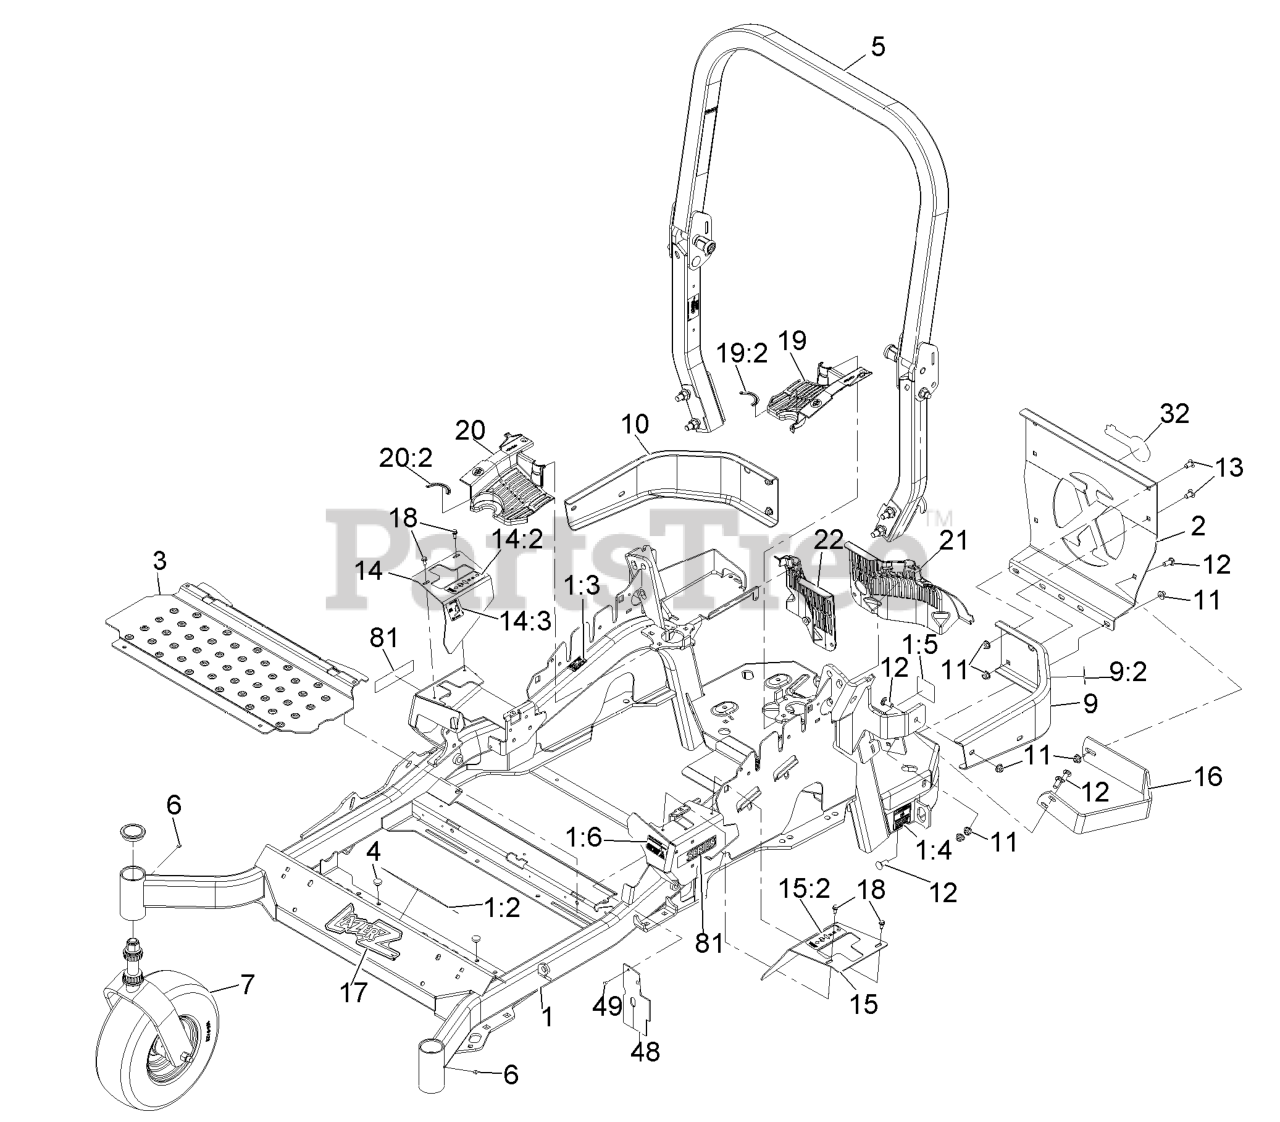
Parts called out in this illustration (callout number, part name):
1	MAIN FRAME ASM
1:2	DECAL-SLOPE
1:3	DECAL-CAUTION
1:4	DECAL-BELT DRIVE
1:5	DECAL-SPARK ARRESTER
1:6	DECAL-FUEL FILL
2	PLATE,REAR GUARD
5	ASM,ROPS SERVICE EXMARK
7	Caster Wheel Asm
9	LH BUMPER ASM
9:2	DECAL-CAUTION
10	BUMPER-RH
11	NUT-HF, NI
12	SCREW-CARR
13	SCREW-CARR
14:2	DECAL-MOTION CONTROL
15	LH MOTION CONTROL COVER ASM
15:2	DECAL-MOTION CONTROL
17	DECAL,LAZER MODEL
18	SCREW-HWH
19	LH HYDRO GUARD ASM
19:2	DECAL-HYDRO OIL
20	RH HYDRO GUARD ASM
20:2	DECAL-HYDRO OIL
21	GUARD-HYDRO, REAR (LH)
22	GUARD-HYDRO, REAR (RH)
48	DEFLECTOR-AIR FLOW
49	RIVET-POP
81	DECAL-S-SERIES
